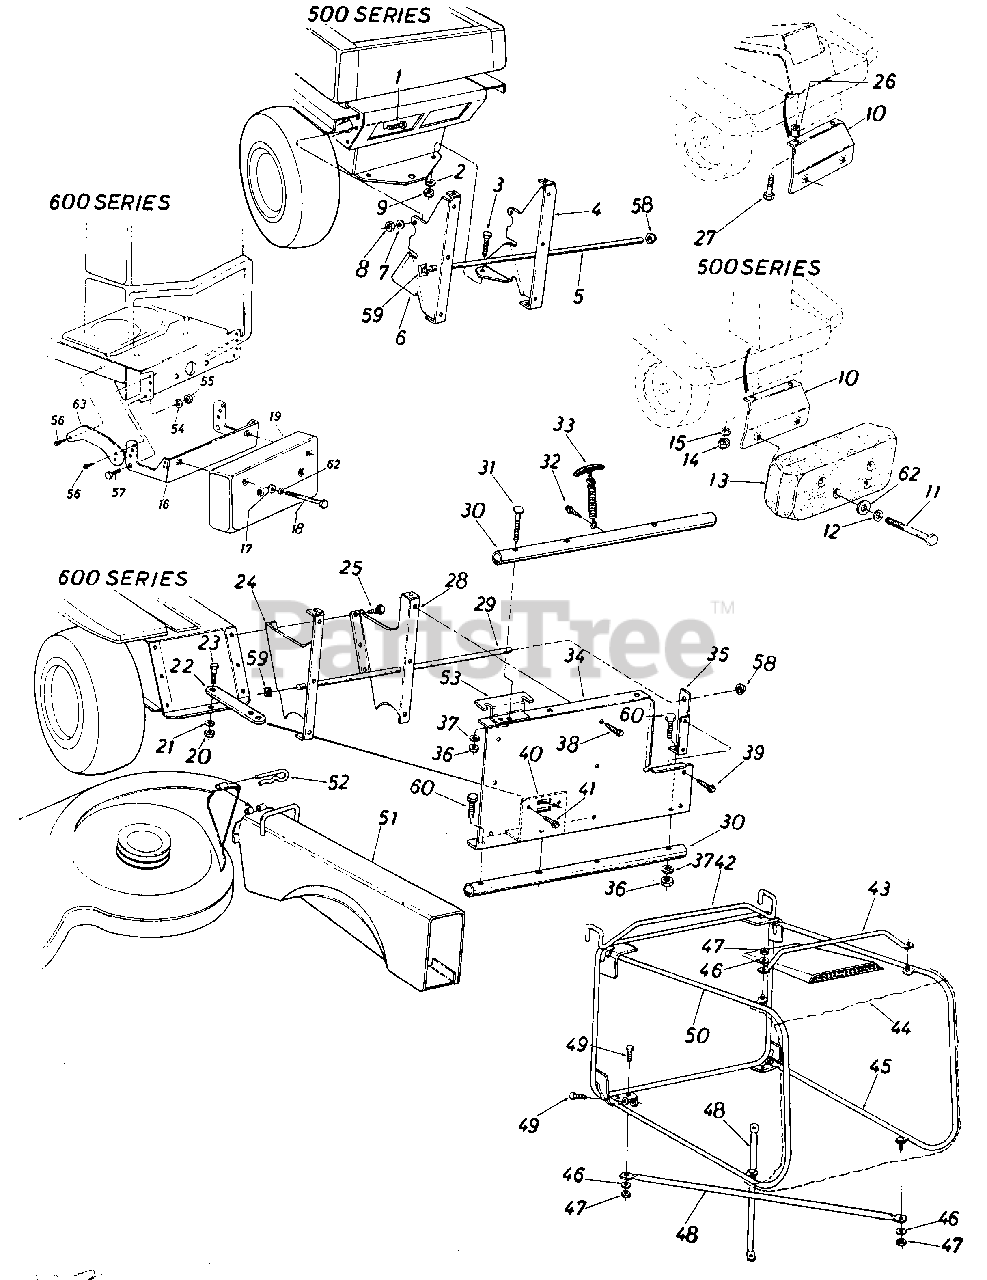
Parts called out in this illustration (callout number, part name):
1	SCREW-HEX 5/16-18 X 1.00
2	WASHER-LOCK-5/16
3	SCREW-HEX 5/16-18 X 1.00
4	BRACKET-SUPPORT-RH
7	WASHER-LOCK-5/16
8	NUT-HEX 5/16-18
9	NUT-HEX 5/16-18
10	BRACKET-SUPPORT
11	SCREW-HEX 3/8 X 4.5 N.C GR. 5
12	WASHER-BELL .400 ID X .88 X .060
13	COUNTERWEIGHT
14	NUT-HEX 5/16-18
15	WASHER-LOCK-5/16
16	BRACKET-WEIGHT
17	WASHER-BELL .400 ID X .88 X .060
18	SCREW-HEX 3/8 X 4.5 N.C GR. 5
19	COUNTERWEIGHT
20	NUT-HEX JAM 1/2-20
21	WASHER-LOCK-1/2
24	BRACKET-SUPPORT-LH
25	SCREW-HEX HD TAP
28	BRACKET-SUPPORT-RH
31	BOLT-CARRIAGE 5/16-18 X 1.75
32	SCREW-HEX WASH HD
33	LOCK ASSY-HOOD
34	ADAPTER-GRASSCATCHER
35	BRACKET-SUPPORT-RH
36	NUT-HEX 5/16-18
37	WASHER-LOCK-5/16
38	SCREW-HEX WASH SF TAPP
39	SCREW-HEX WASH SF TAPP
40	BRACKET-HITCH
41	SCREW-HEX WASH SF TAPP
42	FRAME-CATCHER
43	HANDLE-CATCHER
44	BAG-GRASS
47	NUT-HEX CENTER L-1/4-20
48	BRACE-CROSS-BOTTOM
49	SCREW-HEX 1/4-20 C .62
53	PLATE-SUPPORT
54	WASHER-LOCK-7/16
55	NUT-HEX
56	SCREW-TRUSS MACH 5/16-18 X .75
57	SCREW-HEX 7/16-14 X 1.00
59	NUT-PUSH-SPEED .50 DIA
60	SCREW-HEX 5/16-18 X 1.75
62	WASHER-FL
63	TIE-STRAP
